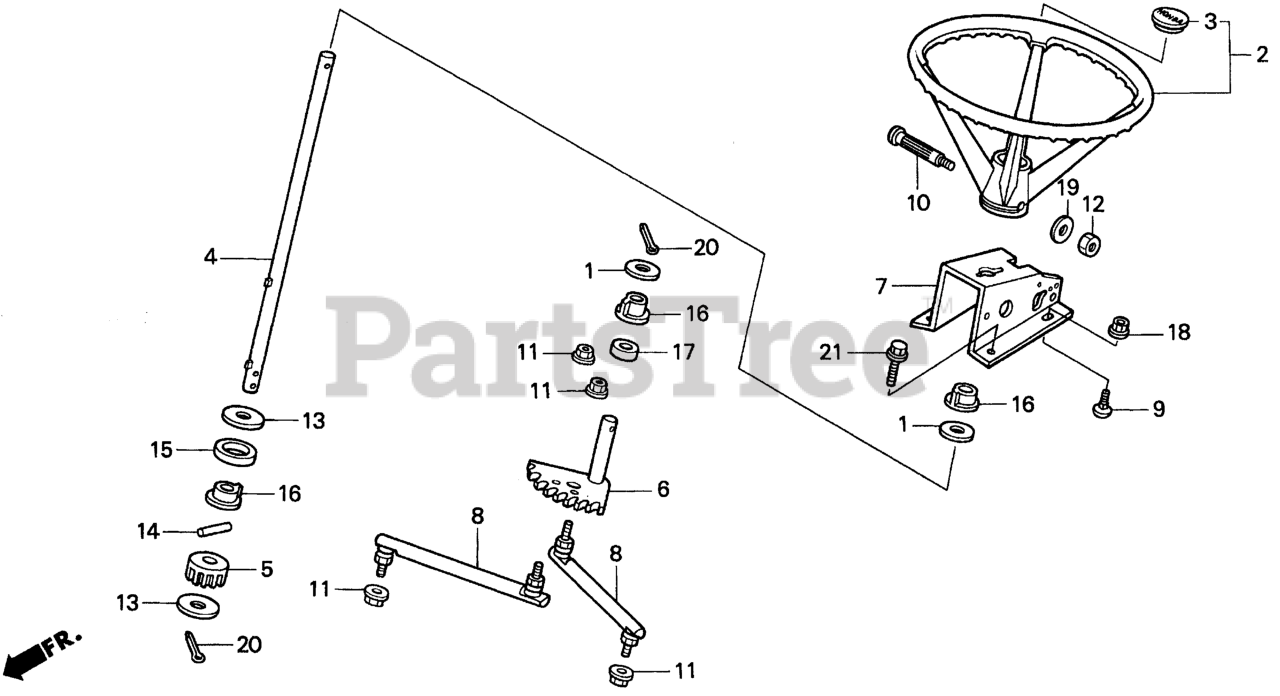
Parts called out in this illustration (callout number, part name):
1	PLATE, PILLION STEP SIDE
2	WHEEL, STEERING
3	CAP, STEERING WHEEL
4	SHAFT, STEERING
5	GEAR, STEERING DRIVE
6	GEAR, STEERING DRIVE
7	BASE, STEERING
9	BOLT, SPECIAL (9X15)
10	BOLT, HUB STEERING
11	NUT, FLANGE (3/8-24)
12	NUT, SELF-LOCK (5MM)
13	WASHER, BRAKE SPRING
14	PIN, STEERING GEAR
16	BUSH, STEERING SHAFT
17	COLLAR, DRIVEN GEAR
18	NUT, FLANGE (8MM)
19	WASHER, PLAIN (5MM)
20	PIN, COTTER (4.0MM)
21	BOLT, FLANGE (8X18)
